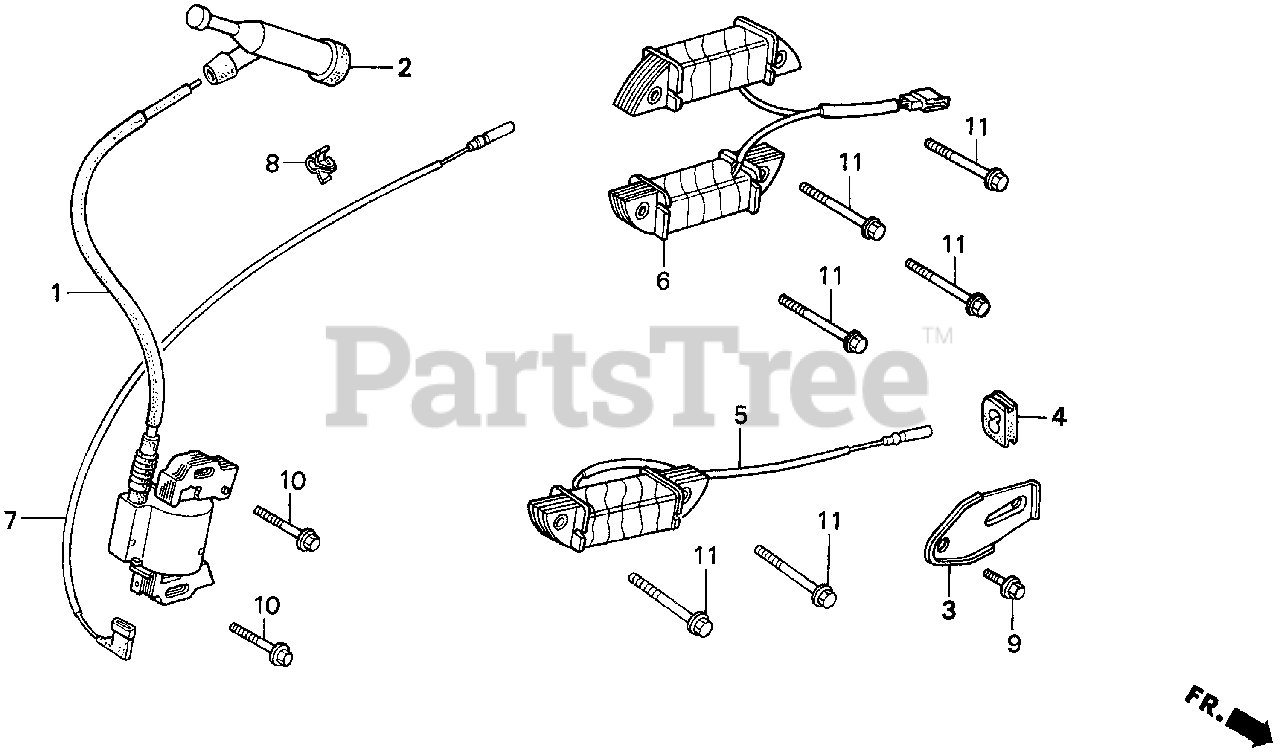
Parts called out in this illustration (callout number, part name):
1	COIL ASSY., IGNITION
2	CAP ASSY., NOISE SUPPRESSOR
4	GROMMET, WIRE
7	WIRE, STOP SWITCH (370MM)
8	HOLDER, STOP SWITCH WIRE
10	BOLT, FLANGE (6X28)
